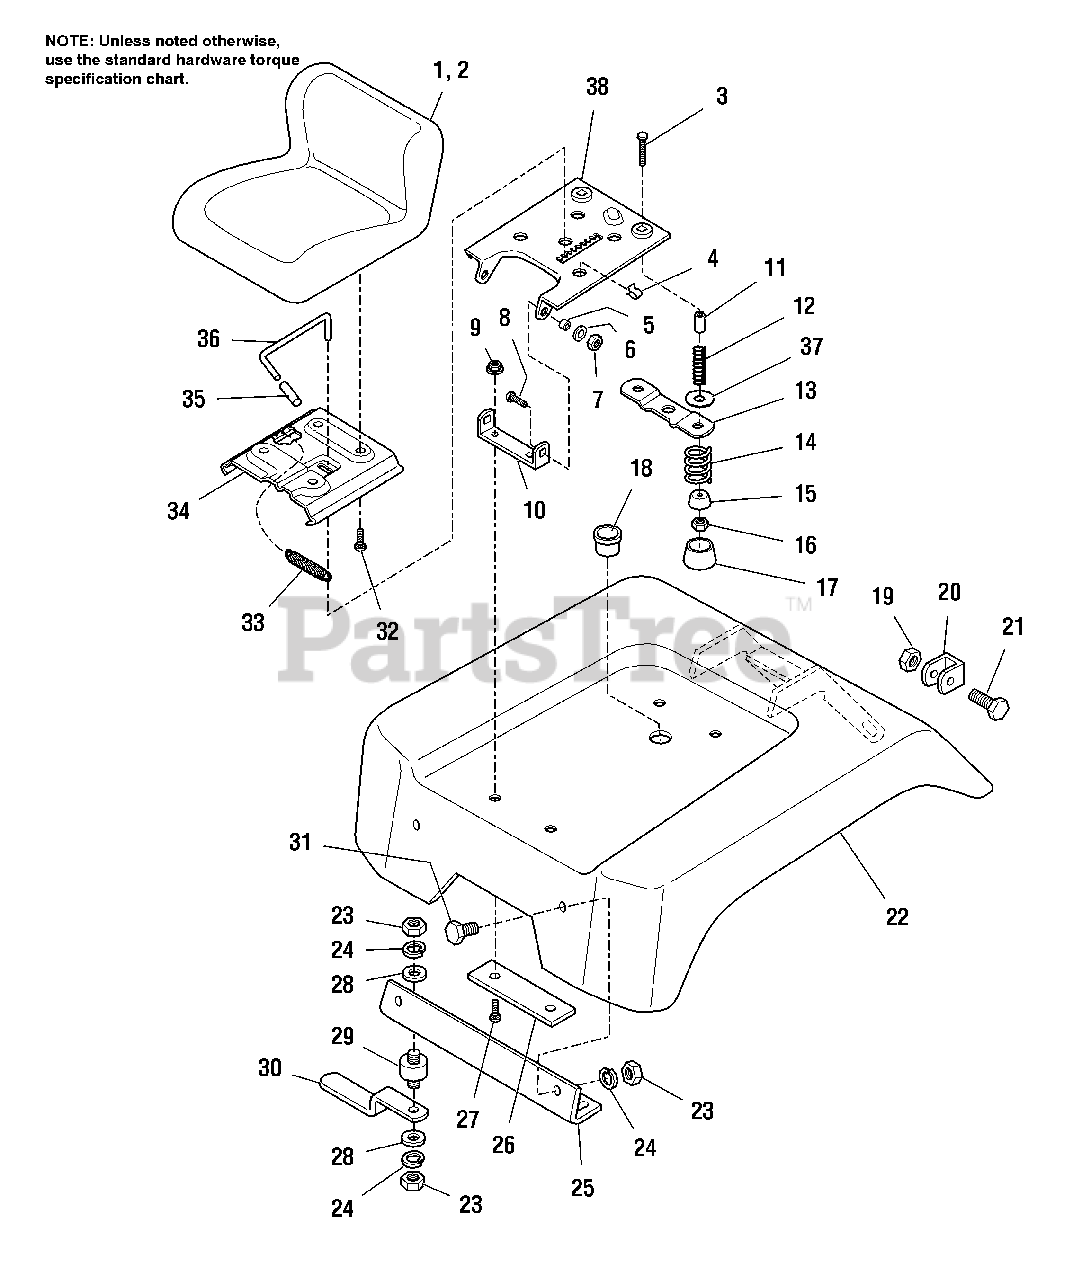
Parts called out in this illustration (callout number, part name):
1	SEAT
2	COVER, Seat
3	CARRIAGE BOLT, 5/16 -16 x 2 Lg
4	CLIP, Speed
6	WASHER, Plain
7	NUT, Hex Nylon Lock, 3/8-16
8	CARRIAGE BOLT, 3/8-16 x 1
9	NUT, Hex Flange, Whiz Lock, 3/8-16
10	BRACKET, Seat Pivot
12	SPRING, Compression
13	PLATE, Switch
14	SPRING, Compression (2" OD)
15	WASHER, Seat Spring
16	NUT, Hex Nylon Lock, 5/16-18
17	COVER, Spring
18	BUSHING, Snap
19	NUT, Hex Lock, 3/8-16
20	STOP, Seat Deck
21	CAPSCREW, Hex Hd, 3/8-16 x 1-1/4
22	DECK ASSEMBLY, Seat (Orange)
22	DECK ASSEMBLY, Seat (Red)
23	NUT, Hex, Full, 5/16-18
24	LOCKWASHER, 5/16
25	BRACKET, Front Seat Deck
26	PLATE, Reinforcement
27	CAPSCREW, Truss Head, Torx Drive, 3/8-16 x 1
28	WASHER, 11/32
29	CONNECTOR, Cushion
30	CLIP, Latch
31	CAPSCREW, Hex Hd, 5/16-18 x 5/8
32	CAPSCREW, Hex Flange Hd, Whiz Lock, 5/16-18 x 1/2
33	SPRING, Extension
34	SLIDE, Seat
35	GRIP, Lever
36	LEVER, Seat Release
37	WASHER, 5/8 x 1-1/4 x 1/16
38	SUPPORT, Seat Pivot
